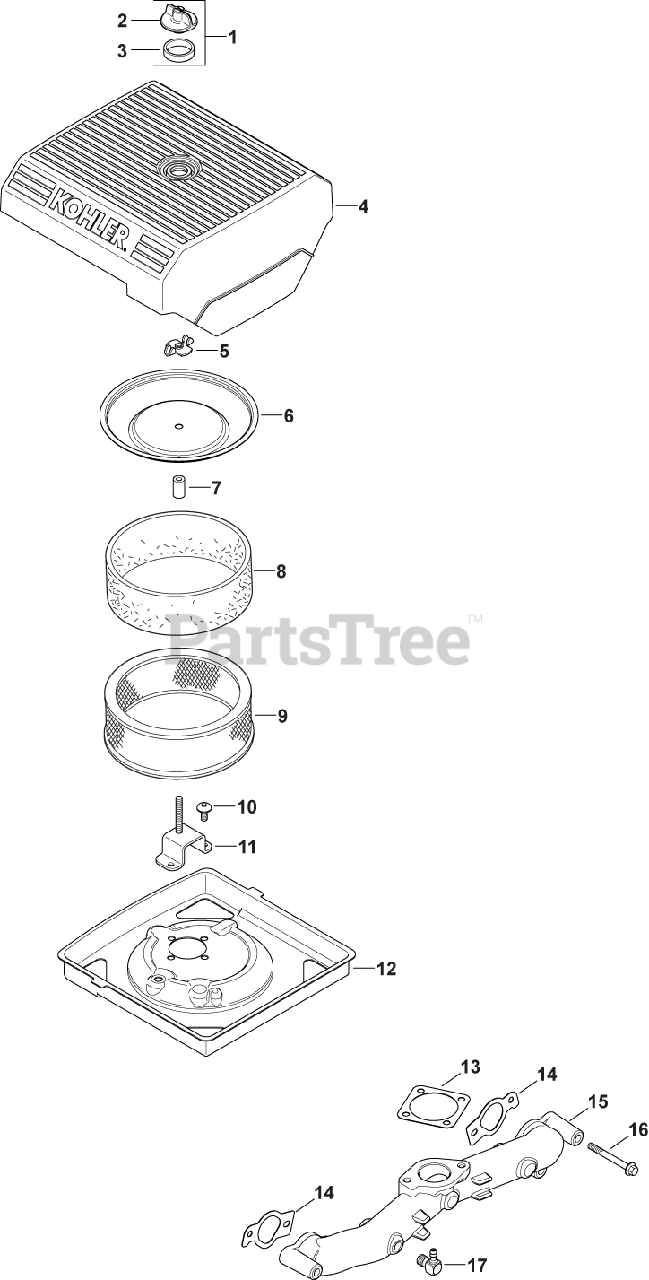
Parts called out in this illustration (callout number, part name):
1	KIT, KNOB W/SEAL
2	KNOB, COVER
4	COVER, AIR CLEANER
5	NUT, WING
6	COVER, INNER AIR CLEANER
7	SEAL, BREATHER
8	PRE-CLEANER (HIGH)
9	ELEMENT, AIR FILTER (HIGH) - Also available Retail Packaged 24 883 03-S1 Air Filter Kit
10	SCREW, IND SLT HD 10-32X1/2"
11	BRACKET, AIR CLEANER
12	BASE, AIR CLEANER
13	GASKET, AIR CLEANER
14	GASKET, INTAKE MANIFOLD USE 24 041 79-S
15	MANIFOLD, INTAKE
16	SCREW, FLG M6X1.0X55
17	CONNECTOR, 90 DEG. - DISCONTINUED
